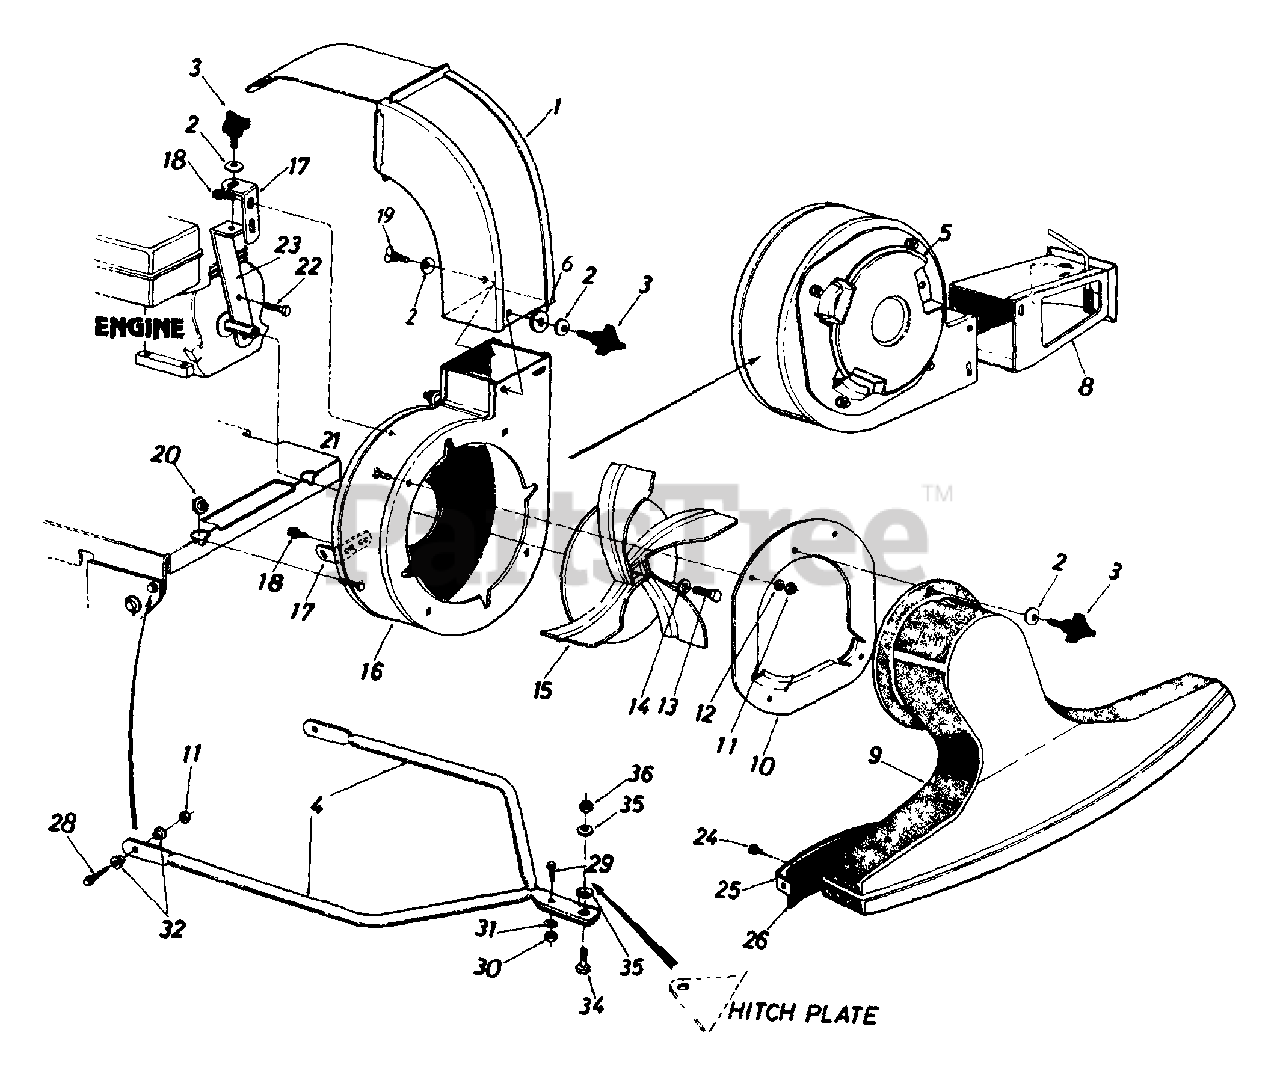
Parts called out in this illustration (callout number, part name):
3	Hand Knob
6	FI-Wash..344" I.D. x 1.125" O.D.
12	L-Wash. 5/16" I.D.
13	Hex Bolt 3/8-24 x 1.25" Lg.
14	L-Wash. 3/8" I.D. H.D.
15	Air Vane Plate Ass'y. w/Pulley
19	Thumb Screw 5/16-18
20	Hex Shoulder Nut .50 I.D.
21	Carriage Bolt 5/16-18 x .62"
22	Hex Locking Bolt 5/16-24 x .75" Lg.
28	Hex Bolt 5/16-18 x 1.00" Lg.
29	Truss Mach. Scr. 1/4-20 x .75"
30	Hex Nut 1/4-20 Thd.
31	L-Wash. 1/4" I.D.
32	Shoulder Spacer
34	Shld. Bolt .496 Dia.
35	Belleville Wash .39" I.D. x 1.12" O.D.
36	Hex Jam L-Nut 3/8-26 Thd.
